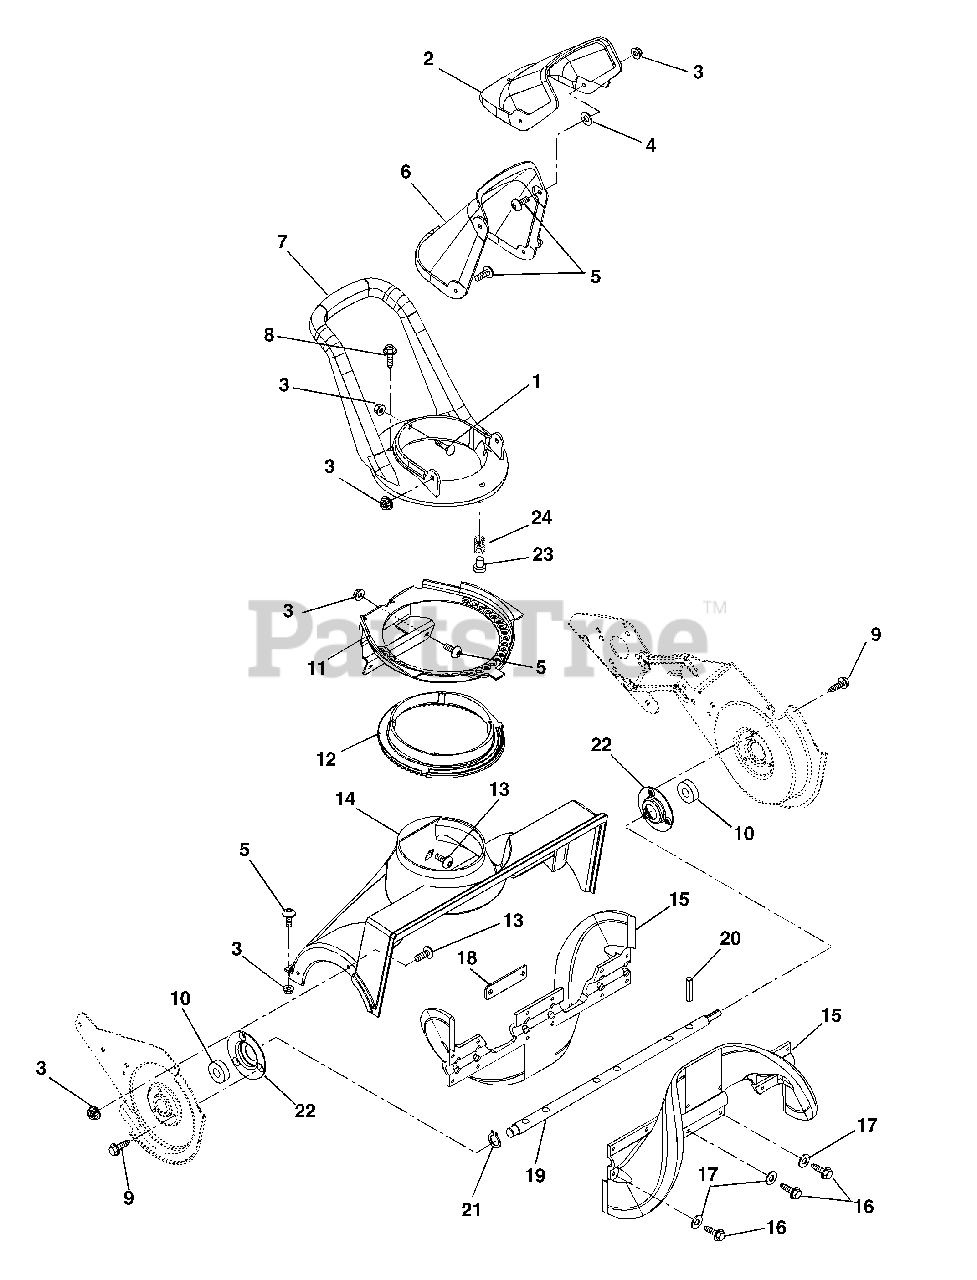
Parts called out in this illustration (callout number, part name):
1	@BLT-RDHDSQNK .25-20X.75 G5YZ
2	DEFLECTOR-DISCHARGE CHUTE ASSY
3	NUT-LK-FLG .250-20 PL BLK
4	WSHR-FL-RBR .31X1.25X.06
5	SCR-MCH .25-20X.75 TXTR YWZC
6	CHUTE-DISCHARGE ASSY
8	SCR TAP 8-18X1.50 SL HWH PL B
9	@SCR-TAP .25-20X.50 HWH TR YWZ
10	BRG-BALL .669X1.575X.47 (6203)
11	BRKT-DISCHARGE CHUTE ROTATION
12	GEAR-DISCHARGE CHUTE SEGMENT
13	SCR-MCH .25-20X.50 TXTR PL
14	HOUSING-IMPELLER ASSY
15	IMPELLER HALF
16	@SCR-TAP .25-20X1.00 HWH TR YZ
17	WSHR-FL-STL .281X1.000X.063
18	PLATE-BOLT,SELF-TAPPING
19	SHAFT-IMPELLER
20	PIN-ROLL .250X1.75 ZINC PL
21	RG-RTNG-EXT .672X.035
22	CUP-BRG
23	RVT- .250 X 1.125 TRUSS YWZC
24	SG-COMP .045X.360X1.75 WLD12.5
25	CABLE TIE LG 5-1/2
